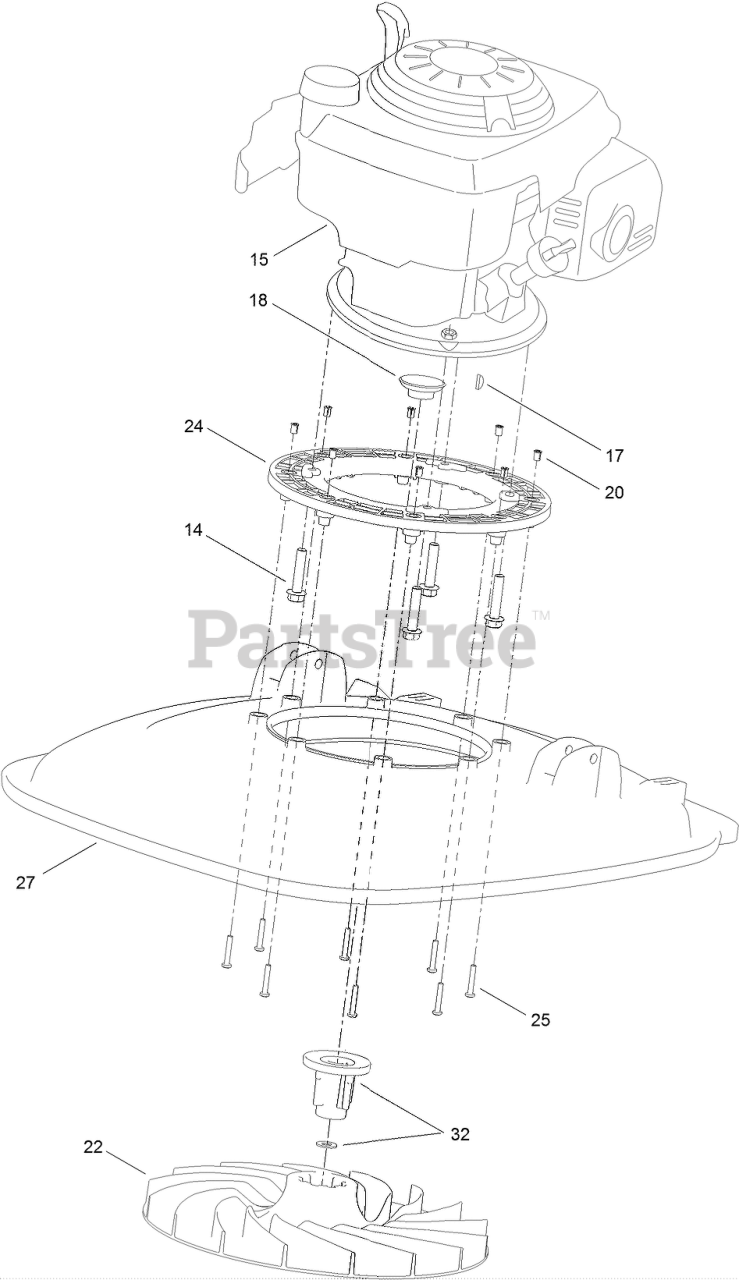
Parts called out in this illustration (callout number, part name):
14	SCREW-TAPTITE
15	ENGINE-Honda
17	KEY-WOODRUFF
18	PROTECTOR-SEAL, OIL
20	INSERT-BRASS
22	IMPELLER
24	FRAME-MOUNTING, ENGINE
25	SET-SCREW
27	DECK
32	DRIVE AND SPACER ASM
